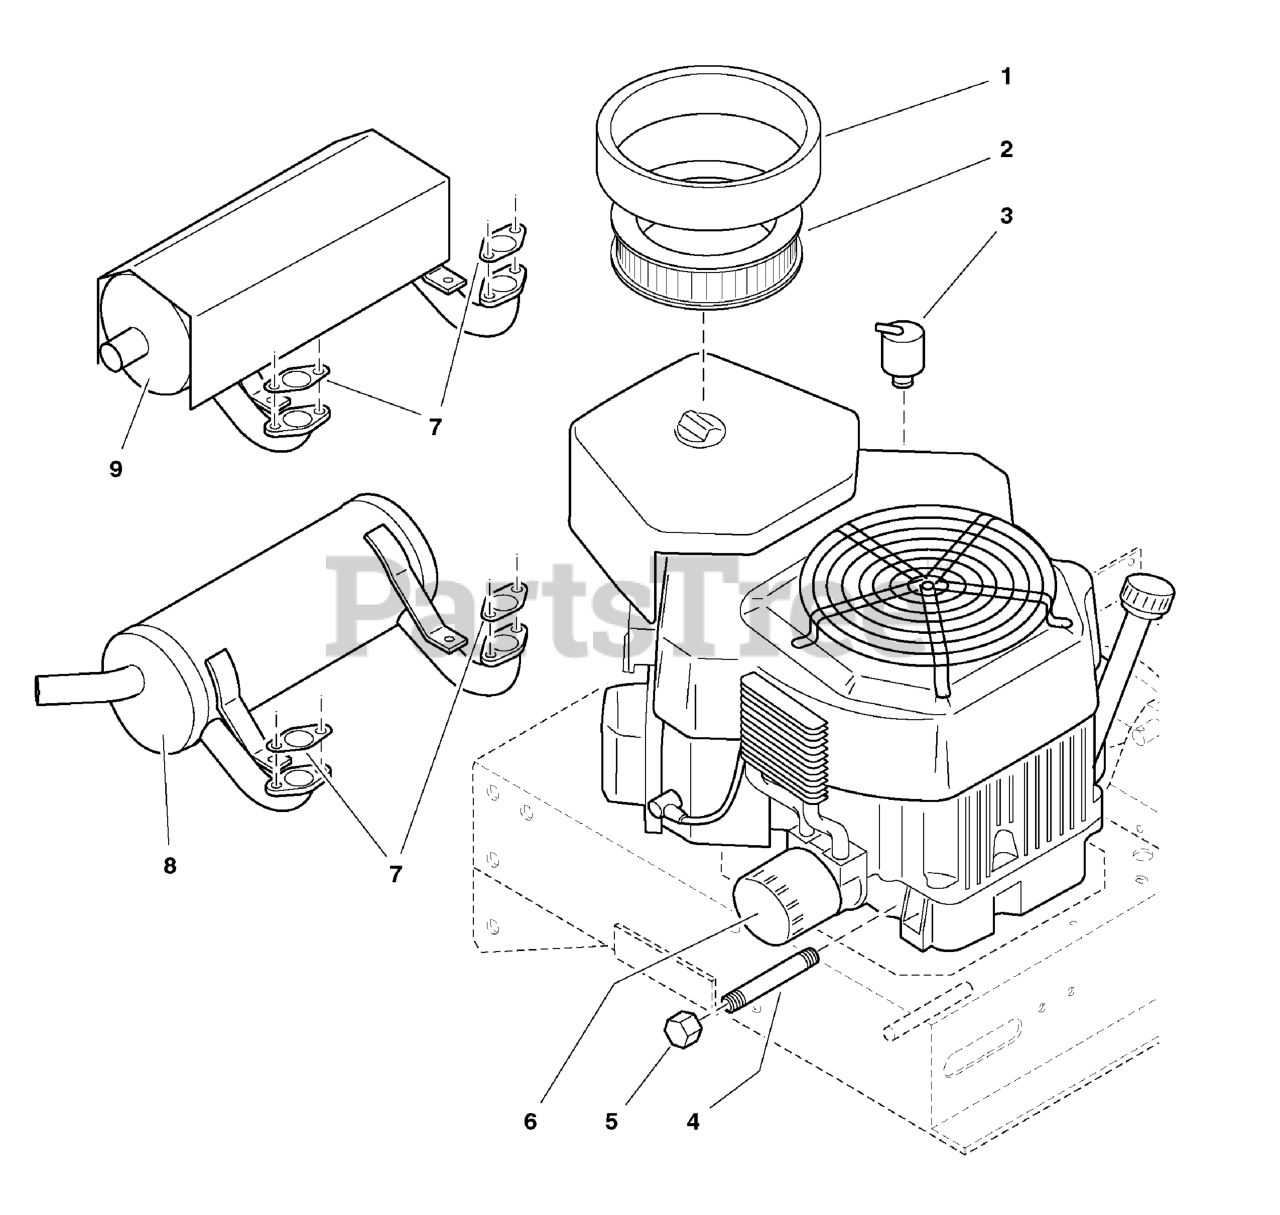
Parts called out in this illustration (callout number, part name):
1	PRE-CLEANER (45 083 01)
2	AIR FILTER (45 083 02)
4	NIPPLE, 3/8 NPT X 4-1/2
5	CAP, 3/8 NPT
6	OIL FILTER (12 050 01)
8	MUFFLER, Kohler
9	MUFFLER (24 068 20) (20HP model only)
